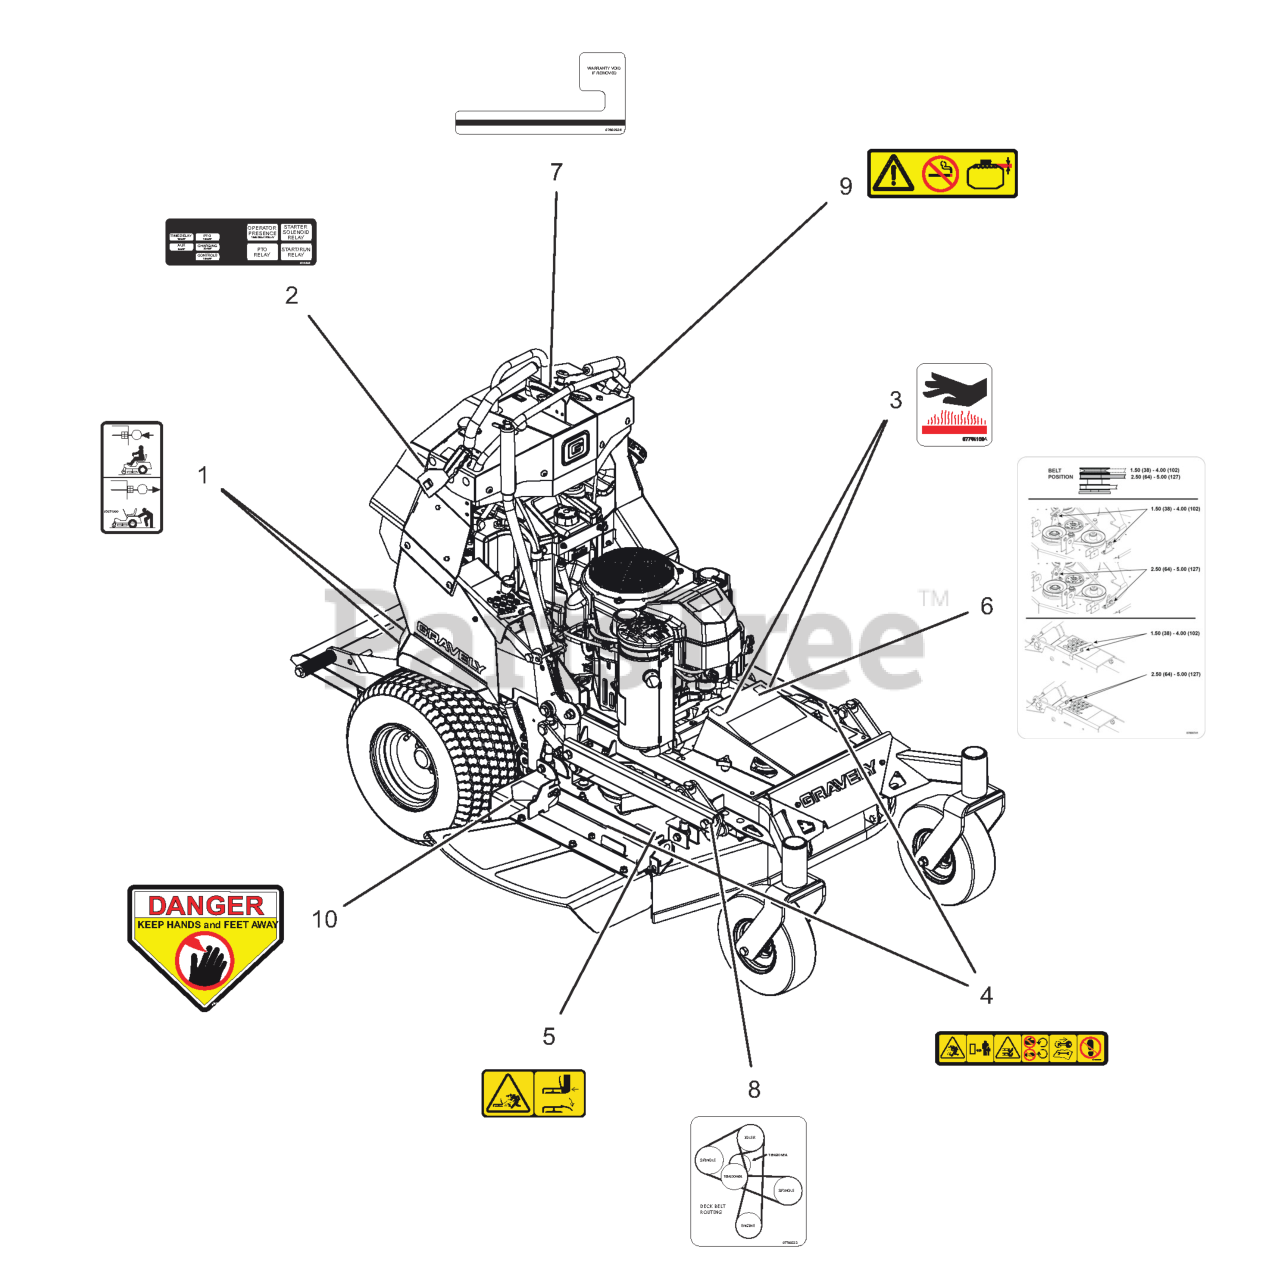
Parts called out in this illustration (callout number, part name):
1	DECAL, TRANSMISSION DISCONNECT
3	DECAL, HOT SURFACE
4	DECAL, DECK SAFETY
5	DECAL, SAFETY - DECK GUARDING
7	DECAL,HOURMETER - SECURITY
9	DECAL, FUEL WARNING
10	DECAL, DANGER
